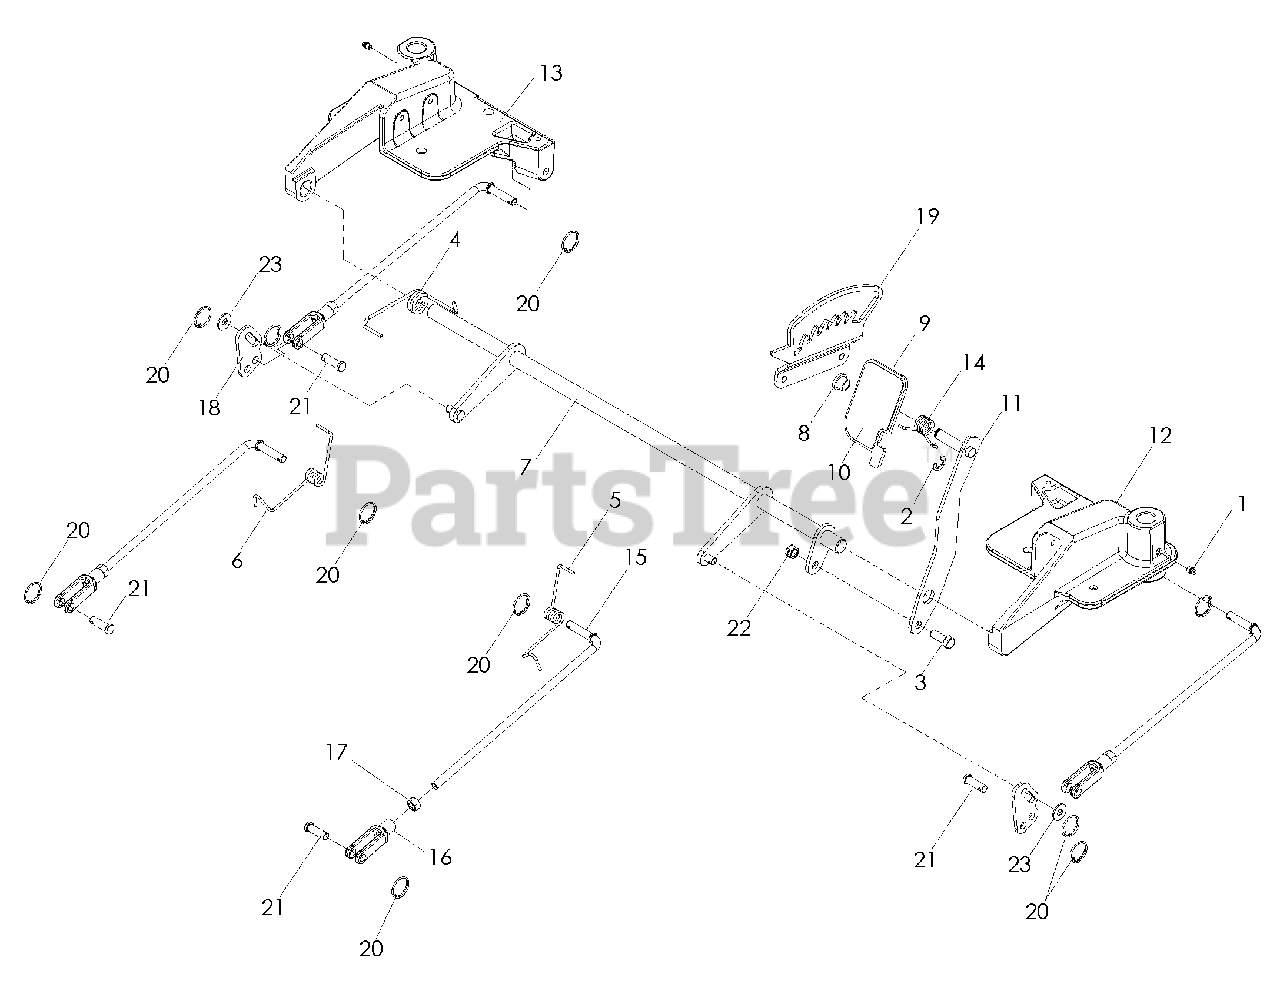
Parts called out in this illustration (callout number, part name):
2	RING-E, 1/2
3	HCS, 3/8-16 x 1, GR8
4	TORSION SPRING
5	SPRING, DECK ROD, RIGHT
6	SPRING, DECK ROD, LEFT
8	BUSHING, NYLON
9	FOOT PEDAL
10	FOOT PAD, NON-SLIP
11	LIFT FOOT LEVER
12	CASTER CASTING, RIGHT
13	CASTER CASTING, LEFT
14	SPRING, PEDAL, LIFT
15	DECK LIFT ROD
16	YOKE, 3/8-24
17	NUT, 3/8-24, GR2
18	CONNECTOR, DECK LIFT
19	HEIGHT PLATE, DECK
20	RING-RETAINING
21	PIN CLEVIS, 3/8 x 1 1/8
22	NUT, 3/8-16, CENTERLOCK
23	WASHER, 5/16
